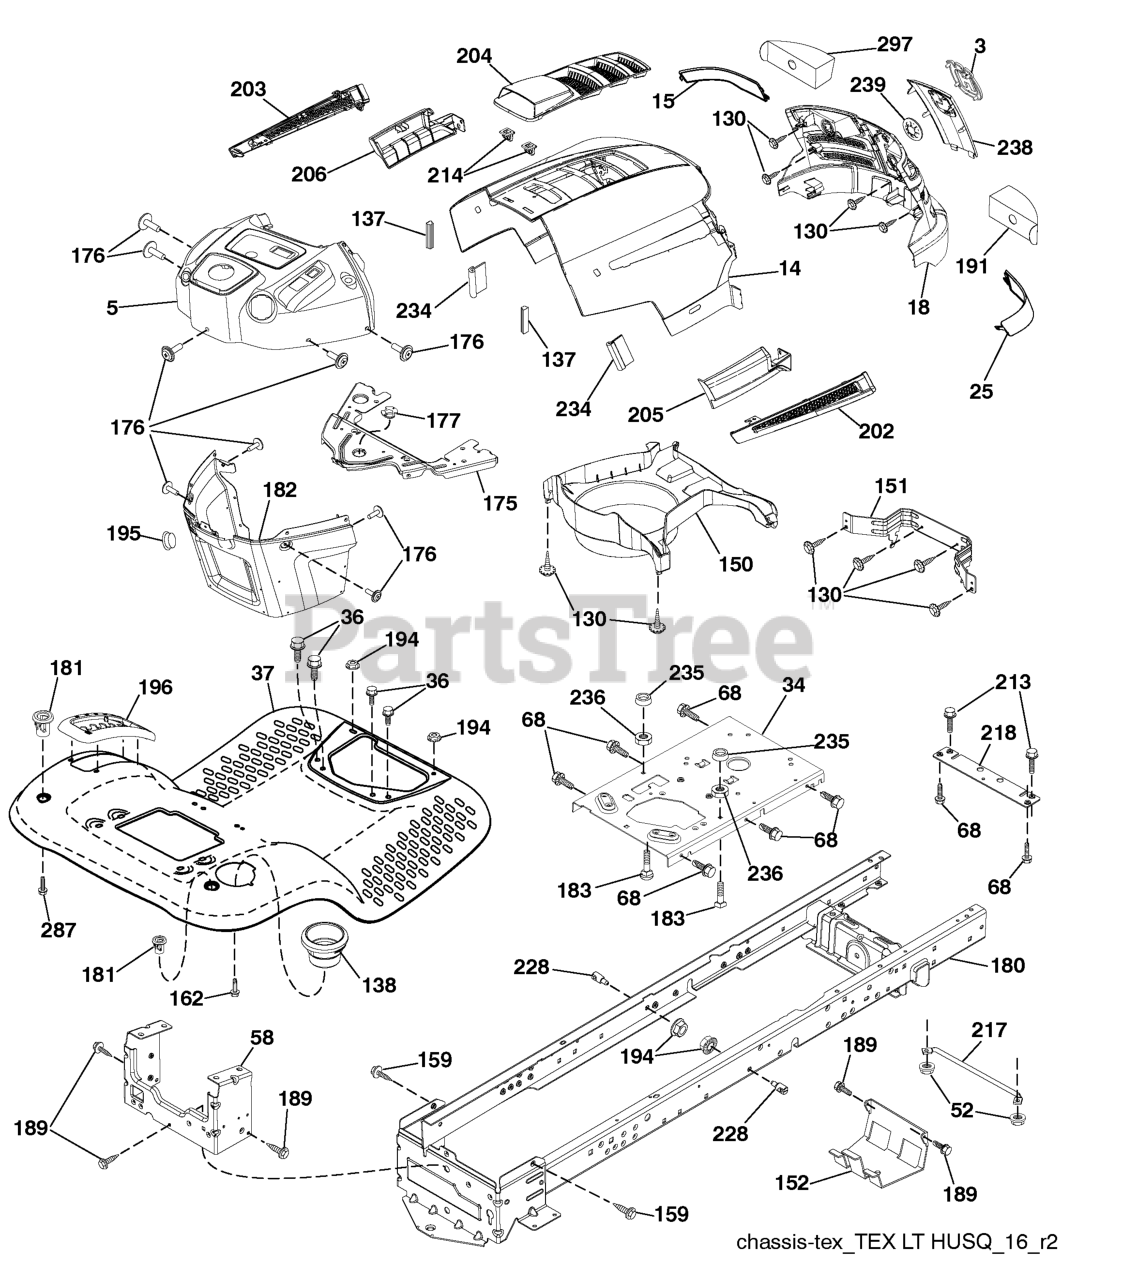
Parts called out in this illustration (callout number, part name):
3	RP LOGO
5	DASH
14	HOOD
15	LENS.HUSQVARNA LT.LH
18	GRILLE.SVC.HUSQVARNA.LT.GREY
25	LENS.HUSQVARNA LT.RH
34	PLATE.ENGINE.WELDED.CHASSIS
36	SCREW 5/16"
37	RP FENDER.TLT.FS.W/CPH.422
52	LOCKNUT
58	DRAWBAR UPPER 2PC SMALL FENDER
68	Screw THDROL 5/16-18 x 1/2
130	SCREW.#10 X 0.750.BOS
137	BUMPER DASH
138	CUPHOLDER.TL.TEX.418
151	BRACKET PIVOT
152	SHIELD.BROWNING.W/TEX
159	SCREW, 3/8-16X3/4
162	SCREW.HI-LO.CONSOLE
175	CROSSMEMBER
176	SCREW.#10-24X5/8.RN.QU
177	BUSHING STEERING
180	CHASS.WLDMNT.TL.12GA/2P.48/54
181	BUSHING.MNT.FEND.CRGO.
182	DASH.LOWER.PREDATOR LT
183	BOLT.5/16-18X1-1/4 FULL THD
189	SCREW
191	INSERT.REFLECTIVE.RH.
194	NUT LOCK HEX FLANGE 5/16-18
195	PLUG DASH
196	RP CONSOLE.ASM.DECKLFT.GR/RBT.
202	VENT SIDE HOOD LH
203	VENT SIDE HOOD RH
204	VENT TOP HOOD
205	SKIRT SIDE RH
206	SKIRT SIDE LH
213	BOLT
214	CLIP.RETAINER.TINNER.
217	ROD.PIVOT.HOOD
218	X-PIECE.HOOD.STOP.NON/
228	STUD.FASTNER.W/ANTI-ROTATE
234	BUMPER.HOOD.TEX.HUSQVARNA
235	SPACER FENDER
236	NUT.CENTERLOCK.5/16-
238	TRIM
287	SCREW 1/4X20
297	INSERT REFLECTIVE
